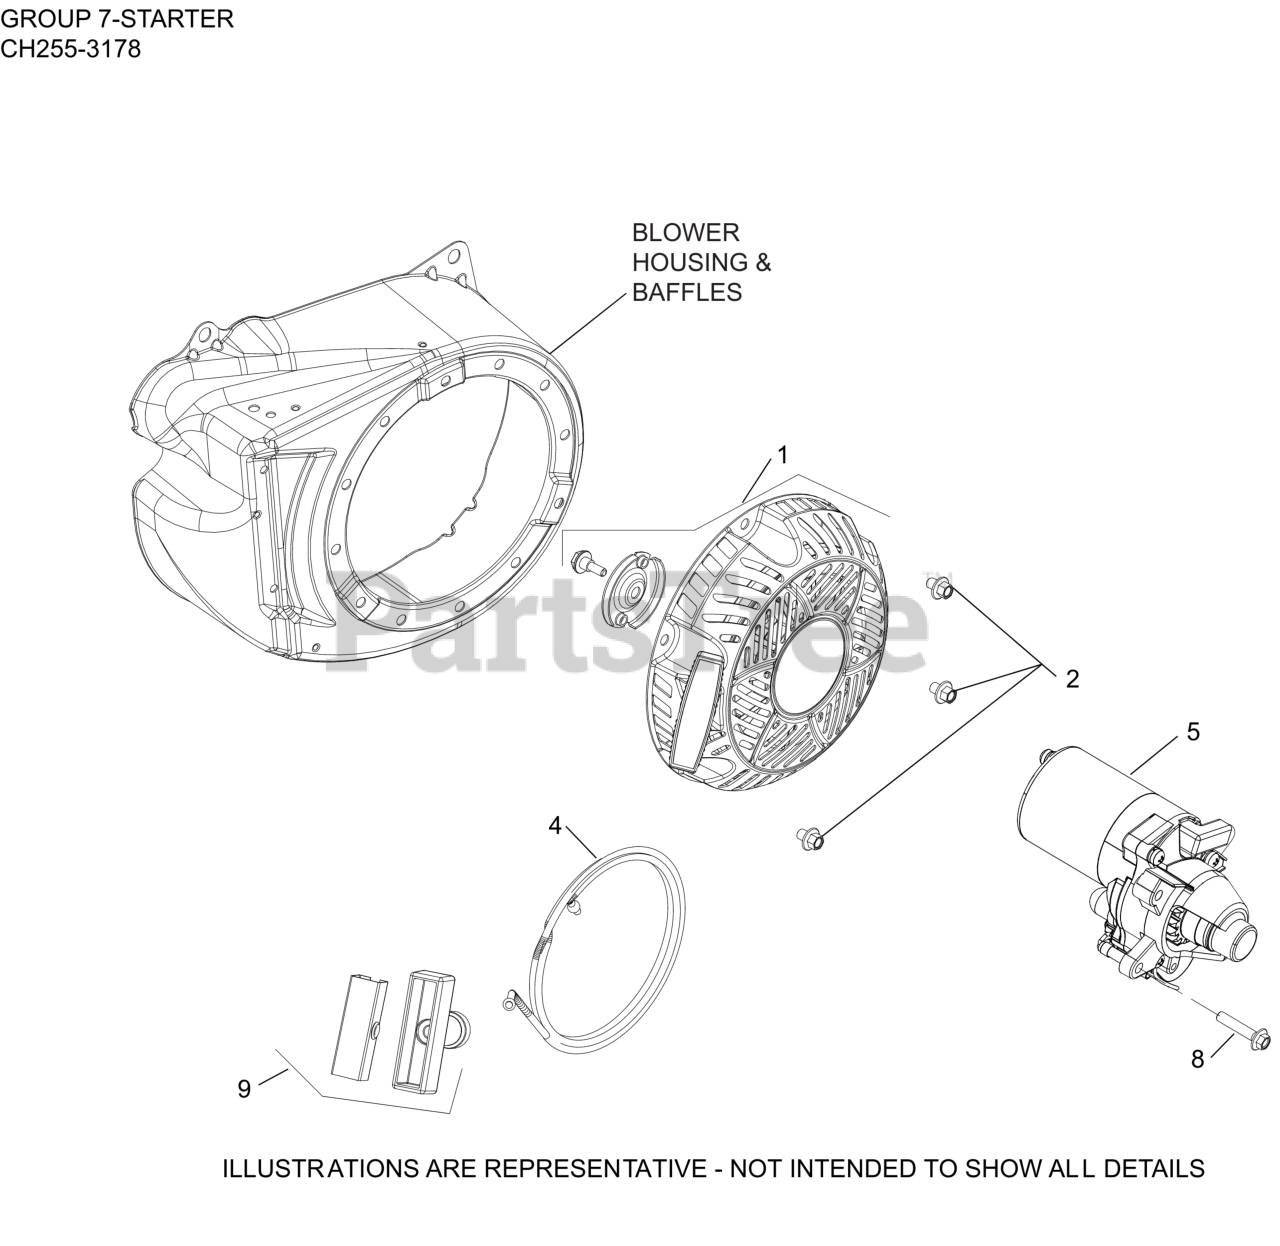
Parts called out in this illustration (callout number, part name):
1	RETRACTABLE STARTER ASSEMBLY
2	SCREW, M6 X 8 HEX FLANGE HEAD
4	ROPE, STARTING
5	ELECTRIC STARTER-BENDIX DRIVE
8	SCREW, STARTER MOUNTING
9	KIT, HANDLE
